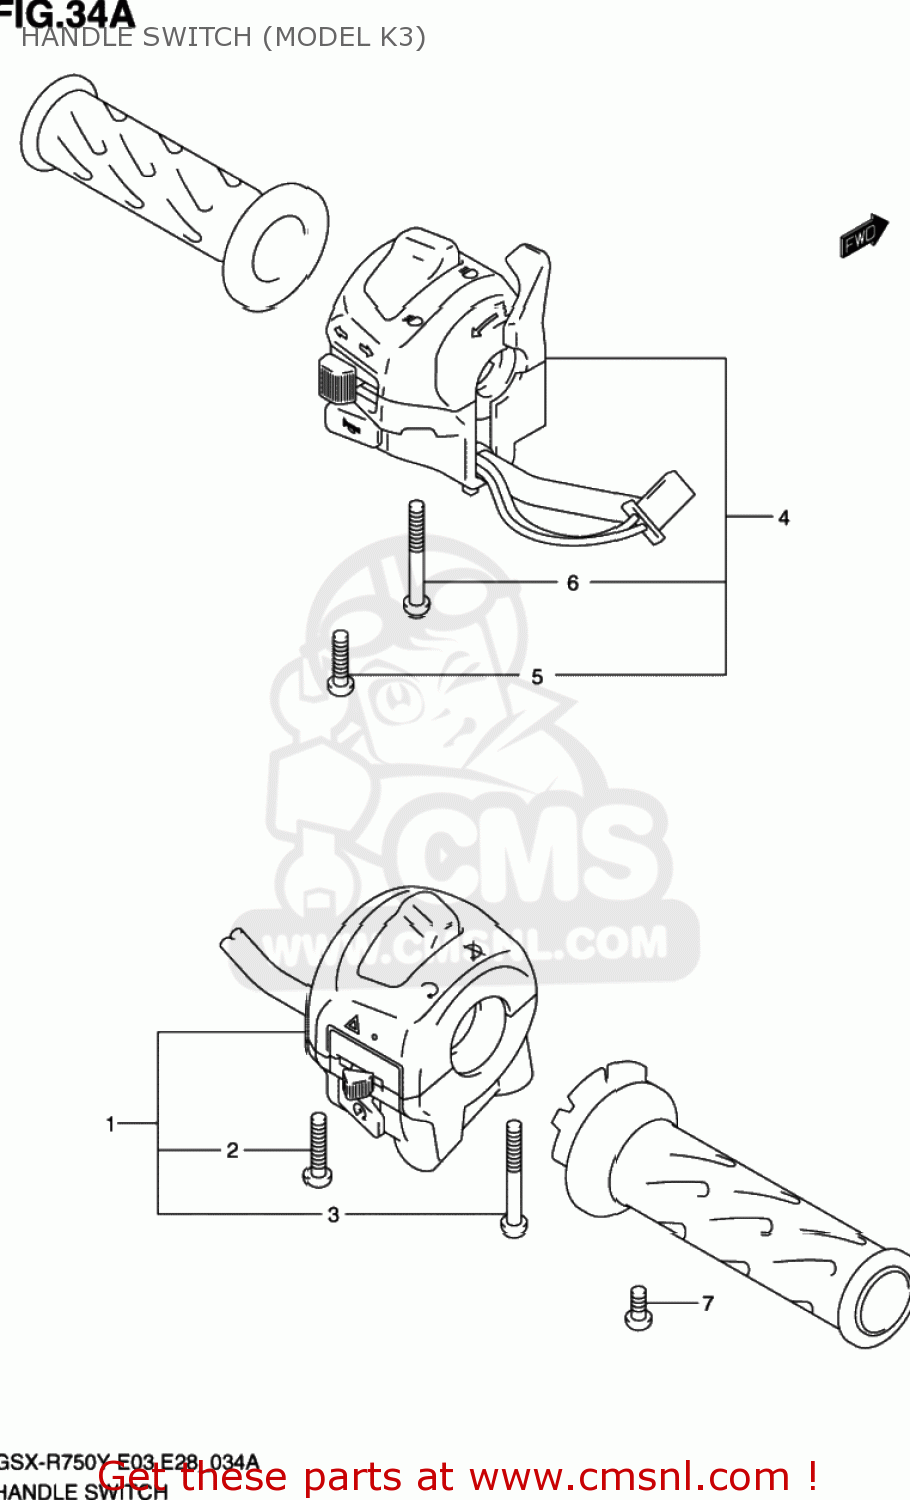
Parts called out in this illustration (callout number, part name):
1	SWITCH ASSY,HANDLE,R
2	SCREW
3	SCREW
4	SWITCH ASSY,HANDLE,L
5	SCREW
6	SCREW, 5X45
7	SCREW
